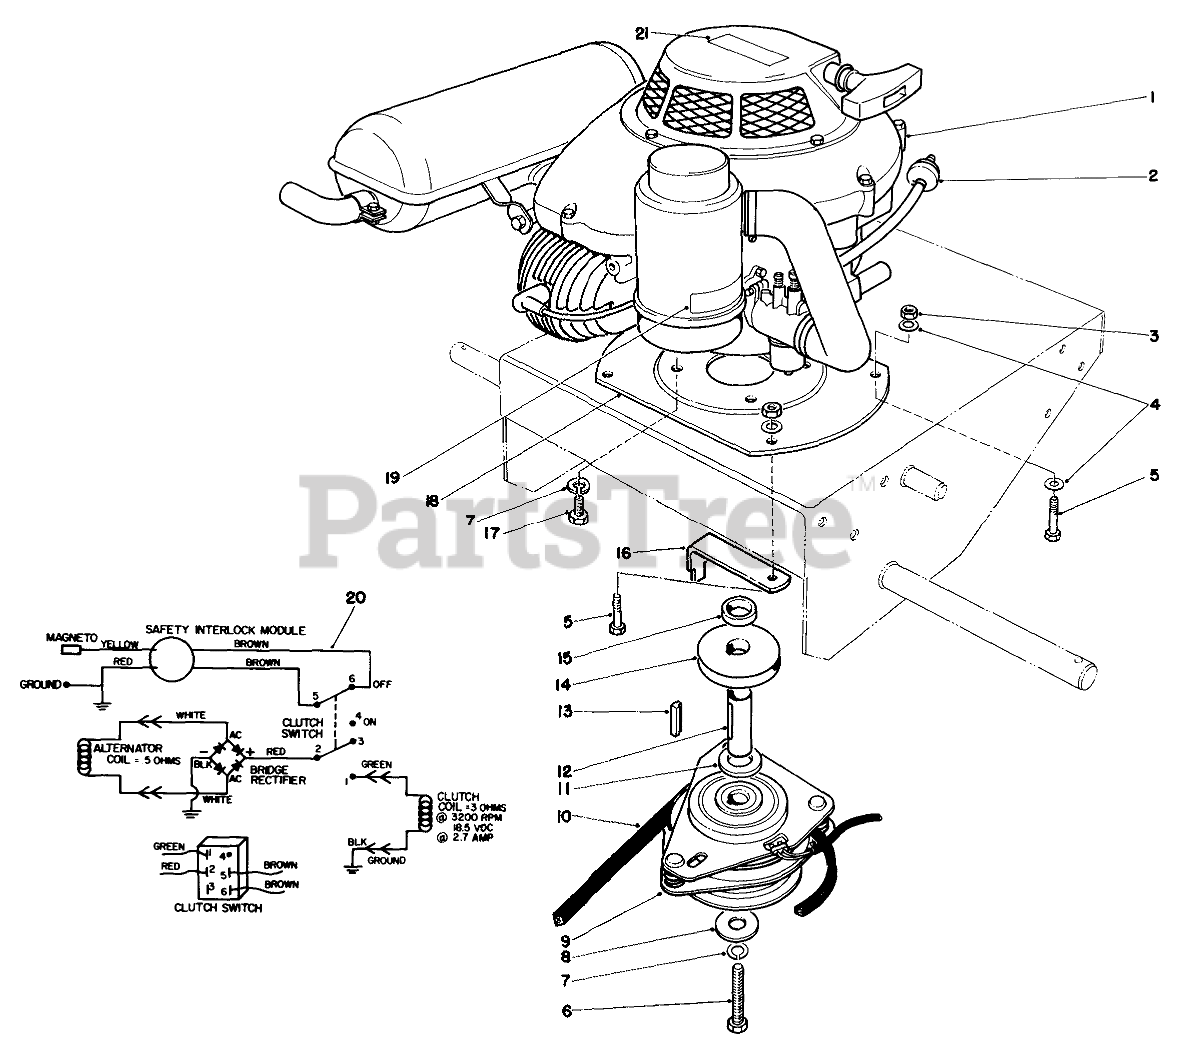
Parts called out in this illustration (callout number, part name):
1	Engine Assembly
2	FILTER-FUEL
3	NUT-LOCK, CONE
4	WASHER-PLAIN
5	SCREW-HH
6	CAPSCREW
7	WASHER-LOCK
8	WASHER-CLUTCH
9	CLUTCH/BRAKE
10	V-BELT, DRIVE
11	SPACER-LOWER
12	Adapter-Crankshaft
13	CRANKSHAFT KEY
14	Pulley-Drive
15	UPPER SPACER
16	Retainer-Clutch
17	CAPSCREW
18	ENGINE PLATE
19	DECAL
20	JLO WIRE HARNESS
21	DECAL
